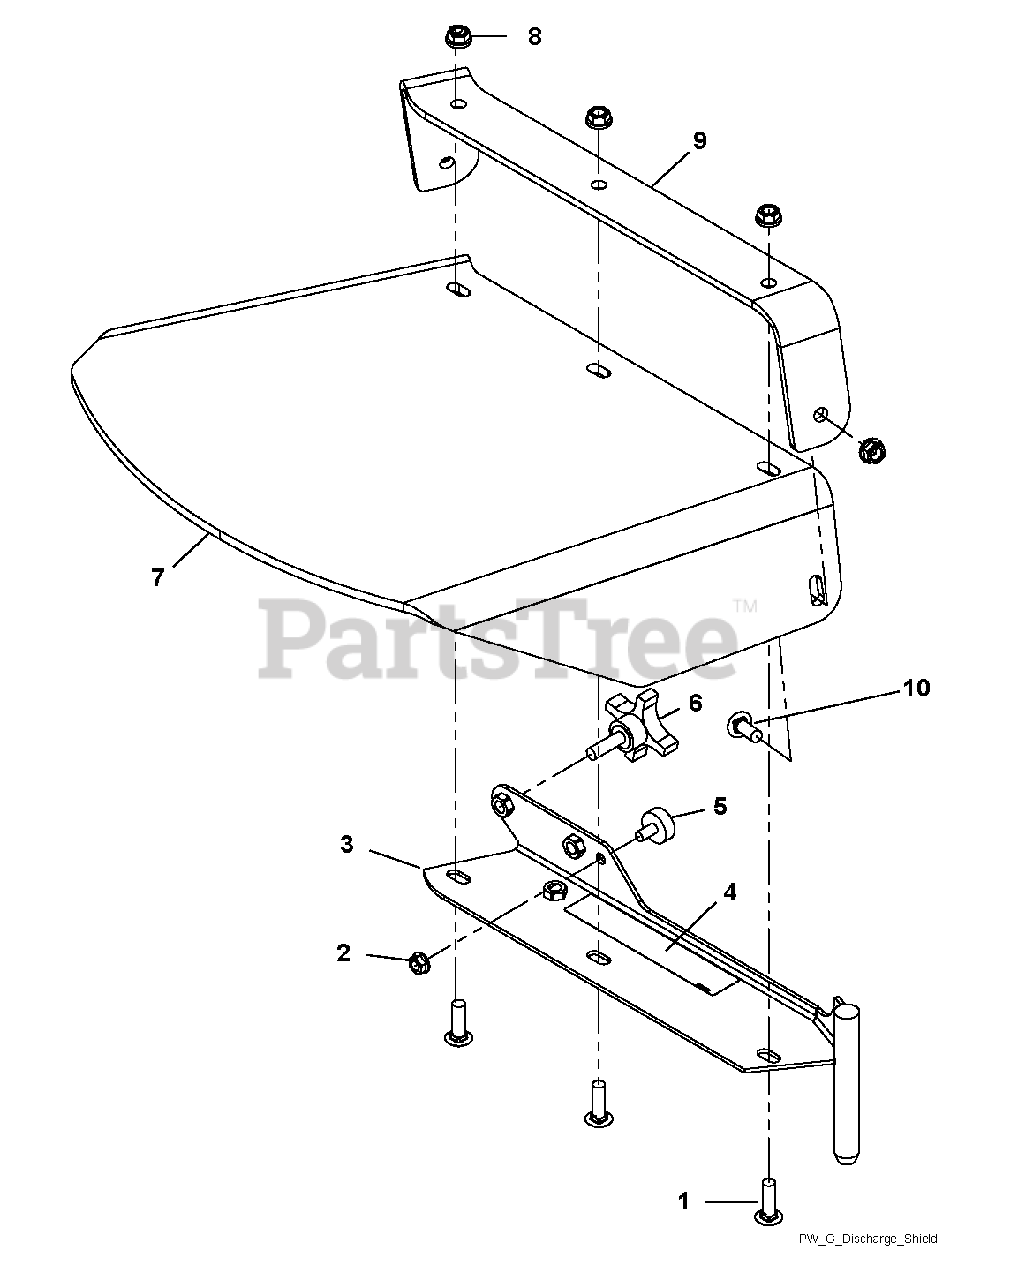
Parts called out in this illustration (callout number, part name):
1	Bolt, Round Head Square Neck .38-16 x 1.25 Grade 5
2	Locknut, .313-18 Whiz
3	Weldment, Discharge
4	Decal, Warning
5	Bumper, Rubber
6	Knob, .375 x 1.25-4 Prong
7	Shield, Walk Rubber Discharge
8	Nut, Spin Lock Flange .375-16
9	Strap, Gravely Walk Rubber Discharge Chute
10	Bolt, .38-16 x 1.0 Round Head Square Neck Grade 5
